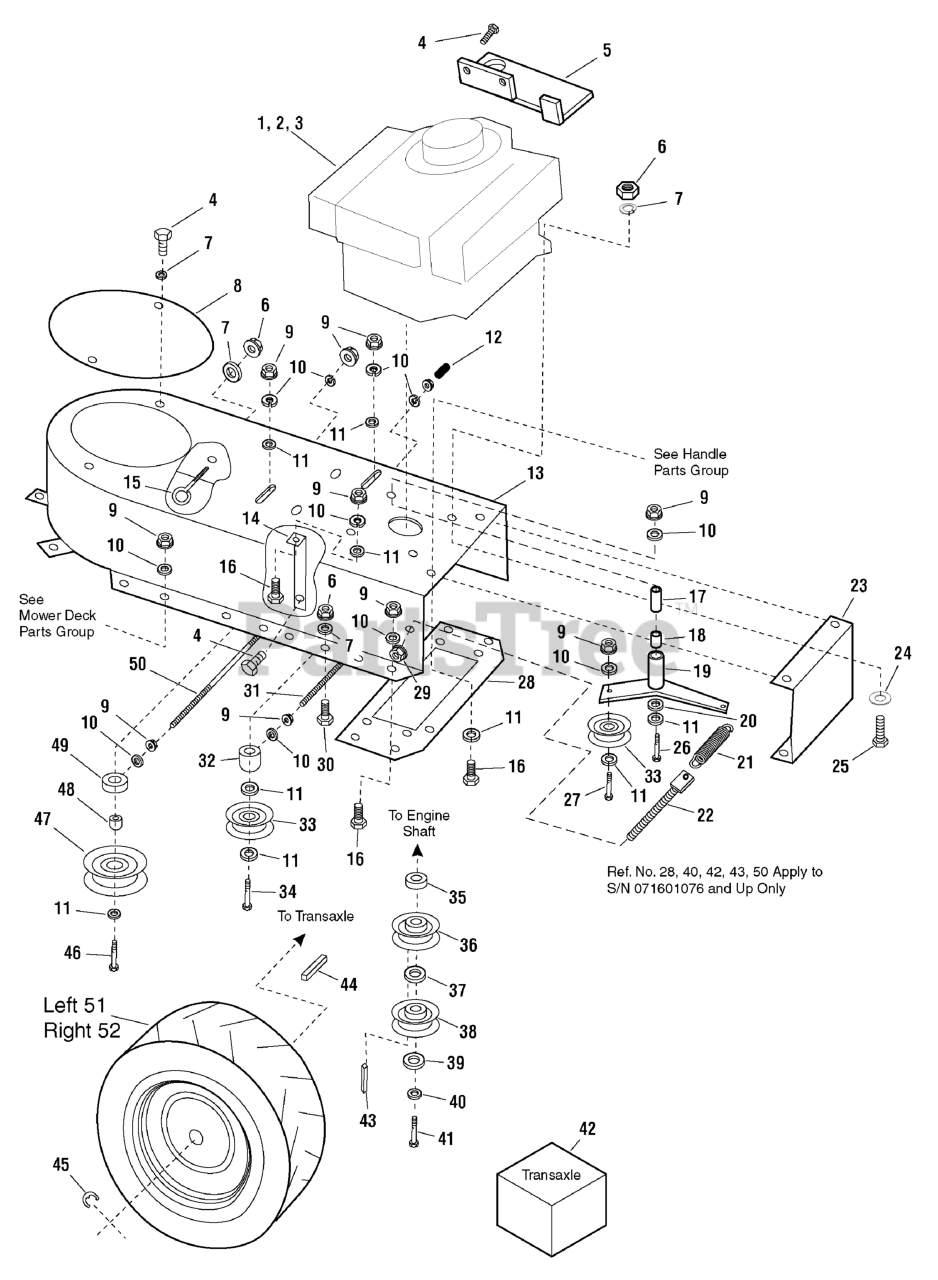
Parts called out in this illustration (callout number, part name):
1	ENGINE, 13.5HP Briggs & Stratton
2	ENGINE, 13HP Honda
3	ENGINE, 15HP Kawasaki
4	BOLT, 5/16-18 x 3/4
5	Auxiliary fuel tank base
6	NUT, Hex, 5/16-18
7	Lockwasher, 5/16
8	Clutch Cover Plate
9	NUT, Hex, 3/8-16
10	Lockwasher, 3/8
11	Flatwasher, 3/8
12	Cap, Black
13	Engine Deck
14	Transmission Forward Mounting Hanger
15	EYE BOLT, 5/16-18x3-1/4
16	BOLT, 3/8-16 x 1
17	Idler Arm Pivot Boss
18	Sleeve Bushing, 3/4 ID
19	Transmission Idler Arm
20	Flatwasher, 1/2
21	Idler Spring
22	Idler Tension Rod
23	Engine deck back cover
24	Flatwasher, 5/16
25	BOLT, 5/16-18 x 1-1/2
26	CAPSCREW, 3/8-16 x 3-1/4
27	BOLT, 3/8-16 x 1-3/4
28	Lower handle mounting plate
29	NUT, Reverse Lock, 3/8-16
30	CAPSCREW, 5/16-18 x 2-1/4
31	Trans belt idler tensioning rod
32	Transmission Idler Boss
33	Idler Pulley
34	BOLT, 3/8-16 x 4
35	Engine Shaft Spacer, 1"
36	Blade Clutch Drive Pulley
37	Engine Shaft Spacer - 1/4"
38	Transmission Drive Pulley
39	Flatwasher Heavy Duty, 7/16
40	Lockwasher, 7/16
41	CAPSCREW, Socket Head, 7/16-20 x 1-1/2
42	Transaxle
43	Key, Engine Shaft, 1/4 x 1/4 x 2-1/8
44	Key, Axle Shaft 3/16 x 3/16 x 1-3/8
45	E clip
46	BOLT, 3/8-16 x 3-1/4
47	Blade clutch idler pulley
48	Idler pulley spacer bushing
49	Blade Clutch Idler Boss
50	Blade Clutch Idler Tensioning Rod
51	Drive Wheel, Left
